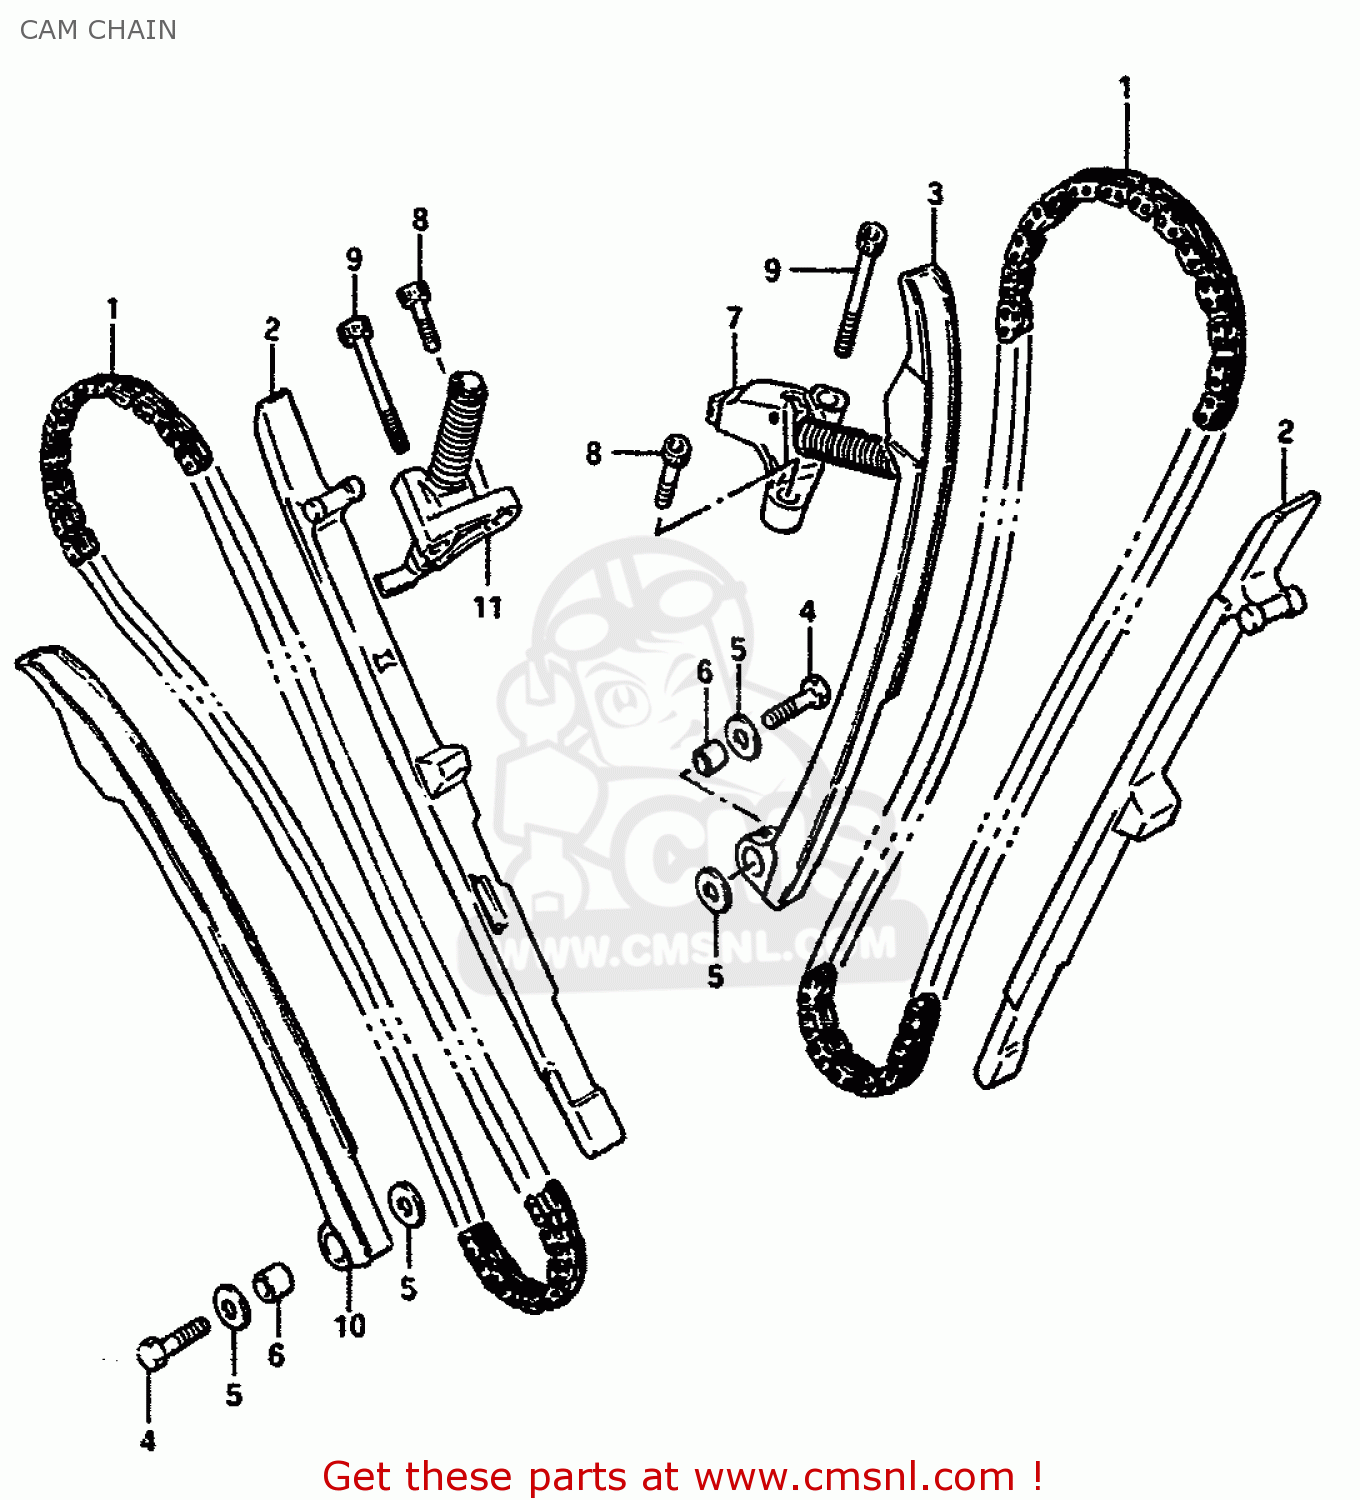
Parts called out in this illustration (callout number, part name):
1	CHAIN,CAMSHAFT DRIVE
2	GUIDE,CAM CHAIN
3	TENSIONER,FR CAM CHAIN
4	BOLT(6X26)
5	WASHER
6	SPACER(6X11X11)
7	ADJUSTER ASSEMBLY,FRONT TENSIONER
8	BOLT
9	BOLT
10	TENSIONER,RR CAM CHAIN
11	ADJUSTER ASSEMBLY,REAR TENSIONER
